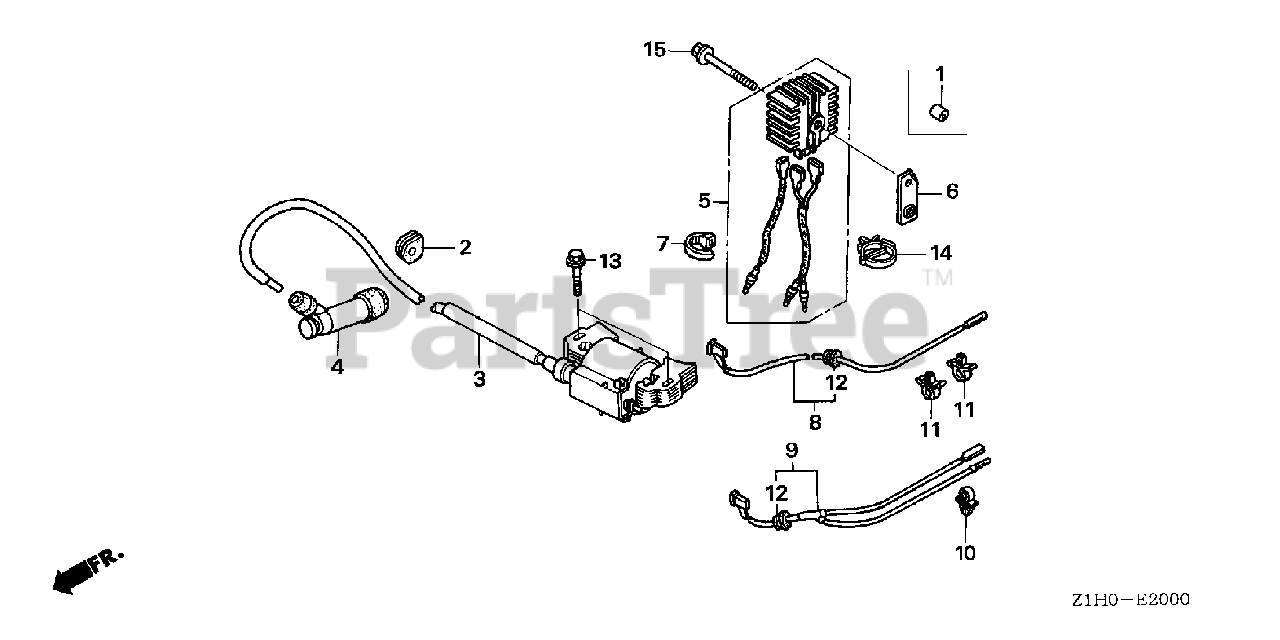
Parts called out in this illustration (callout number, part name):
1	SPACER, AIR CLEANER ELBOW
2	GROMMET, CORD
3	COIL ASSY., IGNITION
4	CAP ASSY., NOISE SUPPRESSOR
5	RECTIFIER ASSY., SILICON
9	WIRE, STOP SWITCH
10	HOLDER, STOP SWITCH WIRE
10	HOLDER, WIRE (FASTEX)
11	CLIP, BRAKE PIPE (A)
12	GROMMET, WIRE CORD
13	BOLT, FLANGE (6X28) (CT200)
14	CLIP, HARNESS
15	BOLT, FLANGE (6X40)
